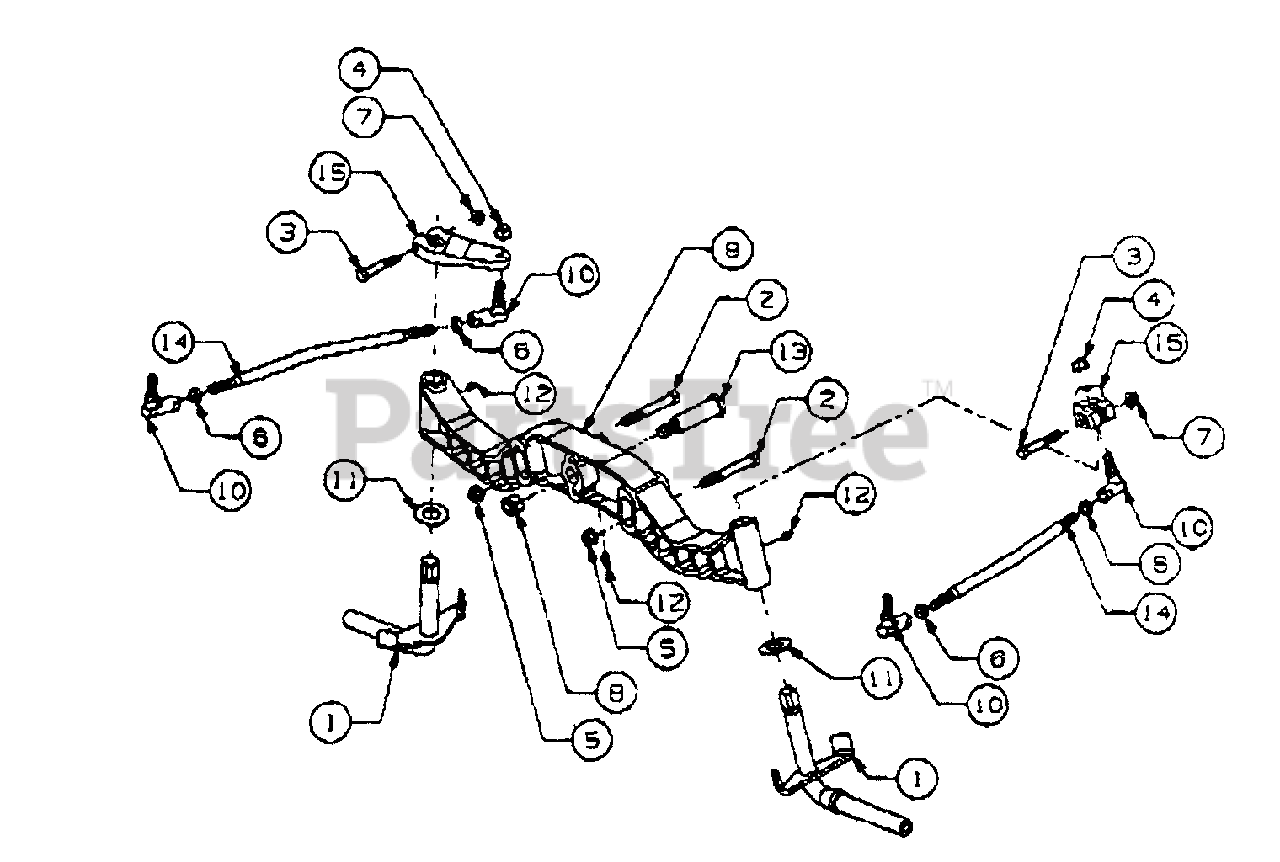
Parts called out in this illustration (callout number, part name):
1	Knuckle Assembly, Steering
2	Screw, Hex Cap, 3/8-16 x 2.75 GR8
3	Screw, Hex Cap, 5/16-18 x 2.0 GR5
4	Nut, Hex Lock, 3/8-24 GR5
5	Nut, Hex Flanged Lock, 3/8-16
6	Nut, Hex Jam, 3/0-24 GR5
7	Nut, Hex Flange Top Lock, 5/18-18
8	Nut, Hex Top Nylon Lock, 1/2-13
9	Axle, Front Pivot
10	Joint, Ball, 3/8-24
11	Washer, Flat, .760 x 1.49 x .06 Thk.
12	Fitting, Lube, 3/16 Drive Type
13	Bolt, Pivot Shoulder, 3/4 Dia x 2.23
15	Arm, Steering
